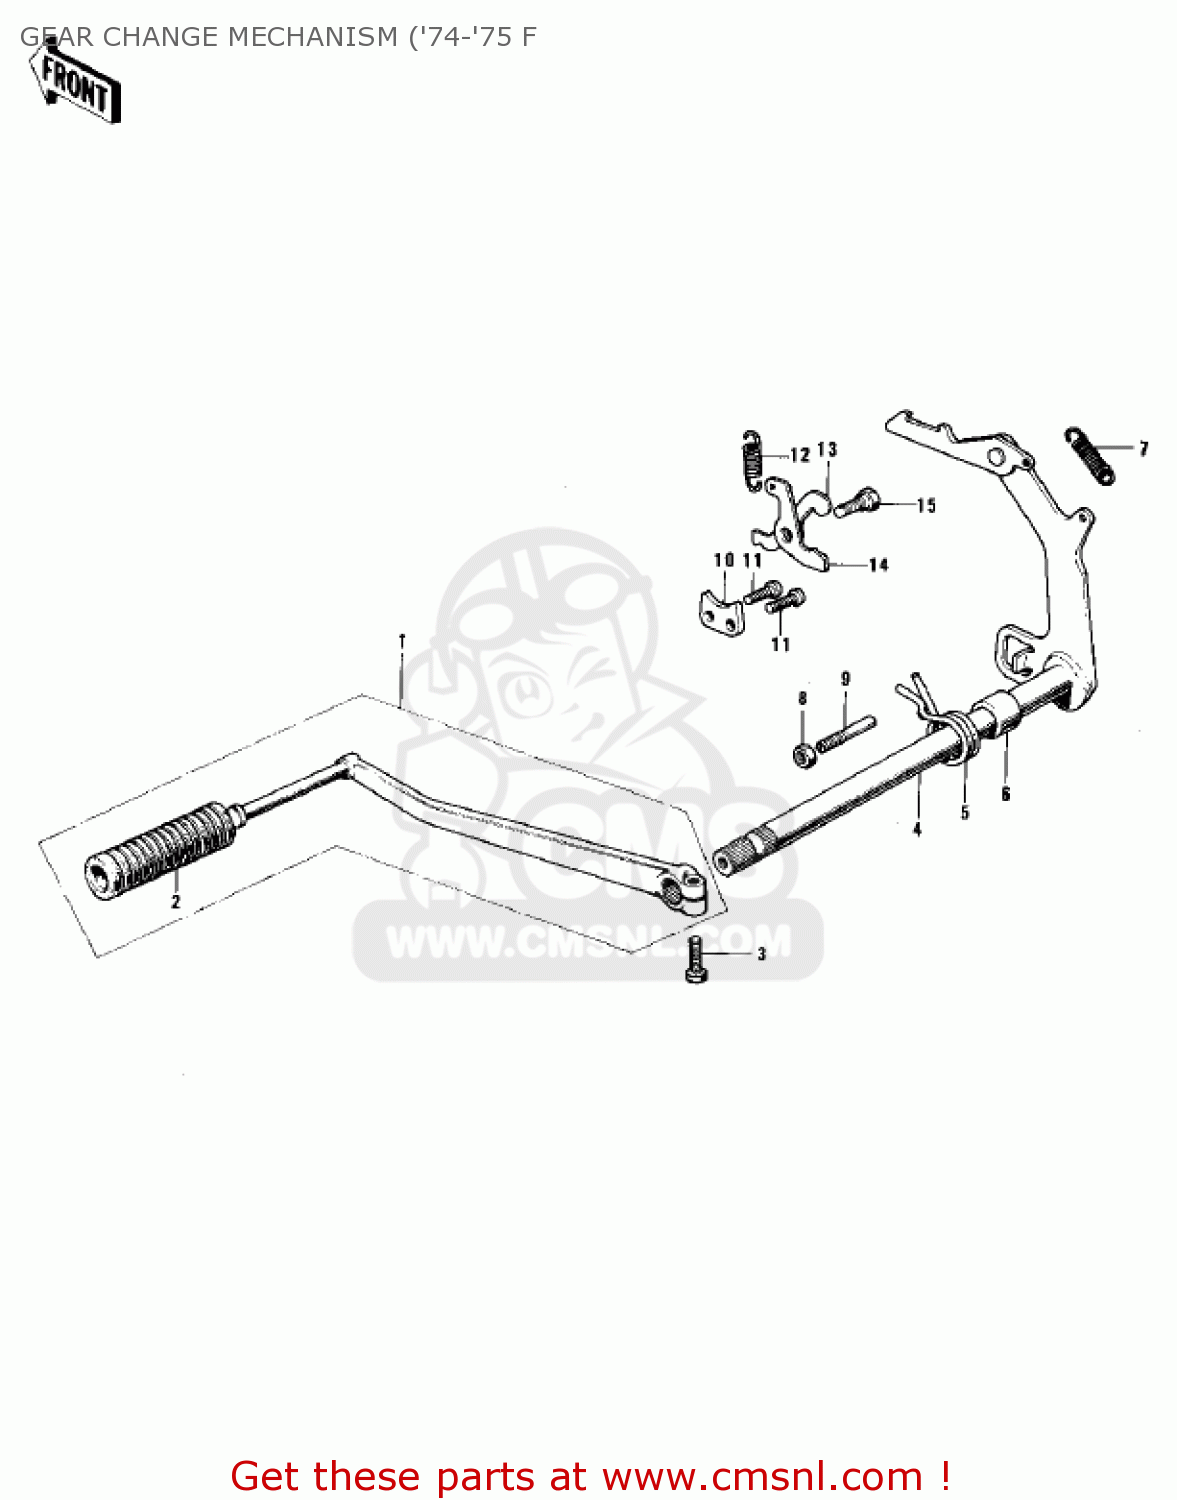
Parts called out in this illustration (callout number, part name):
1	PEDAL-GEAR CHANGE
2	RUBBER-CHANGE PEDAL
3	BOLT 6X20
4	LEVER ASSY-GEAR CHNG
5	SPRING,TENTION
6	COLLAR
7	SPRING,CHANGE LEVER
8	NUT,8MM
9	BOLT,RETURN SPRING
10	PLATE,CHANGE DRUM POS
11	SCREW-PAN HEAD,6X14
12	SPRING-COIL
13	LEVER-CHANGE DRUM,B
14	LEVER-GEAR CHNG DRUM
15	SCREW-PAN HEAD
